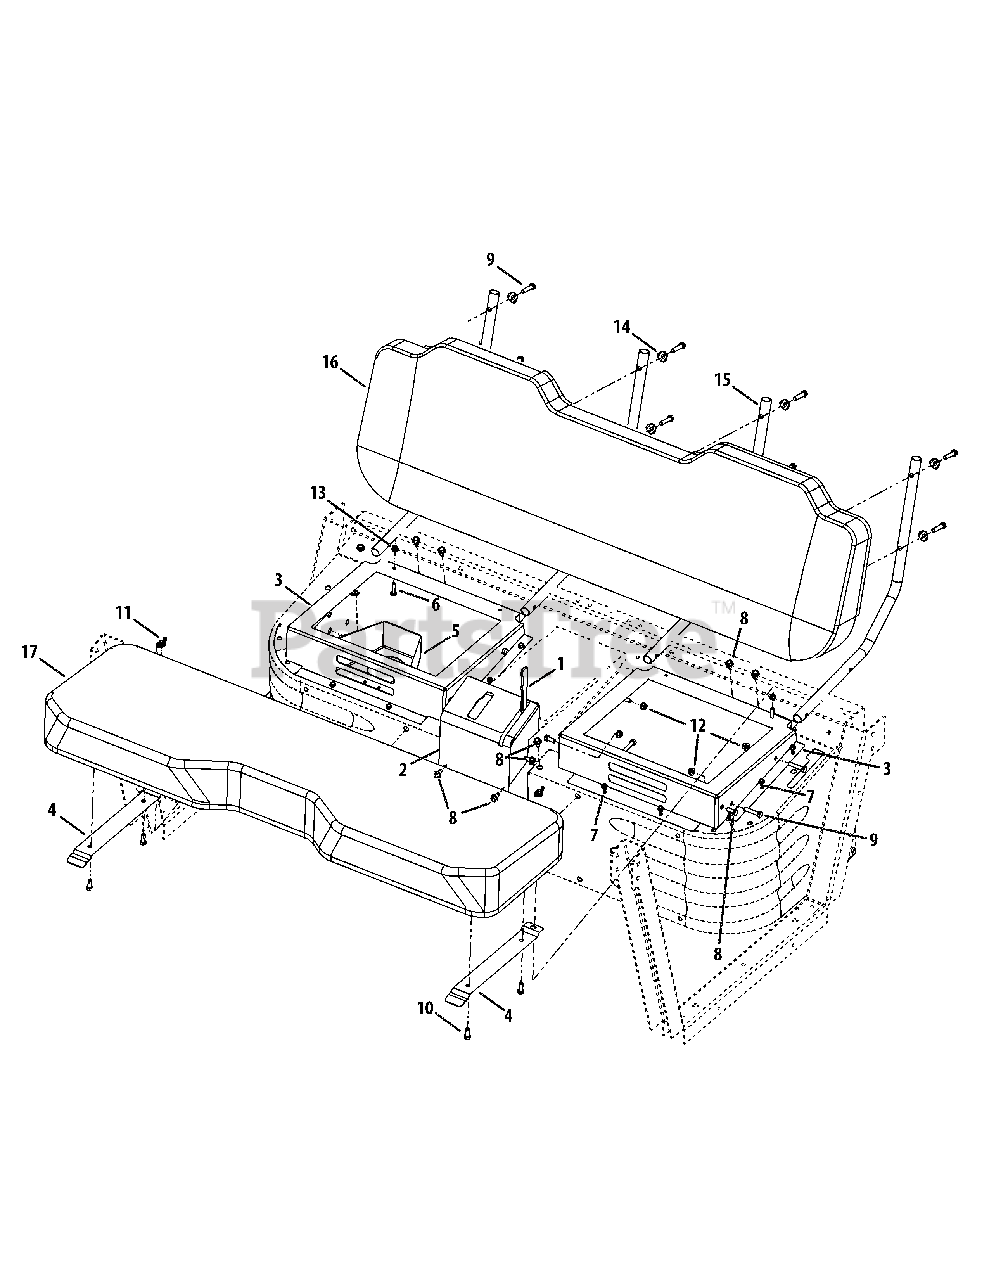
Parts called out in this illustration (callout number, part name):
5	Brkt., Shld., Heat, Bench
6	SCREW 1/4-20 X1.00 GR5
7	Scr., TT, 1/4-20 x .500
8	Scr., TT, 5/16-18 x .500
9	Hhcs., 5/16-18 x 1.50
10	SCREW 5/16-18 x .75 GR5
11	Nut, Wing, 1/4-20
12	Nut, Flglk., 5/16-18
13	Nut, Flglk., 1/4-20
14	Wash., Sdl., .320 x .93 x .060
15	Tube, Mt., Seat, Back
16	Seat, Back, Bench
17	Seat, Bench, Bottom
